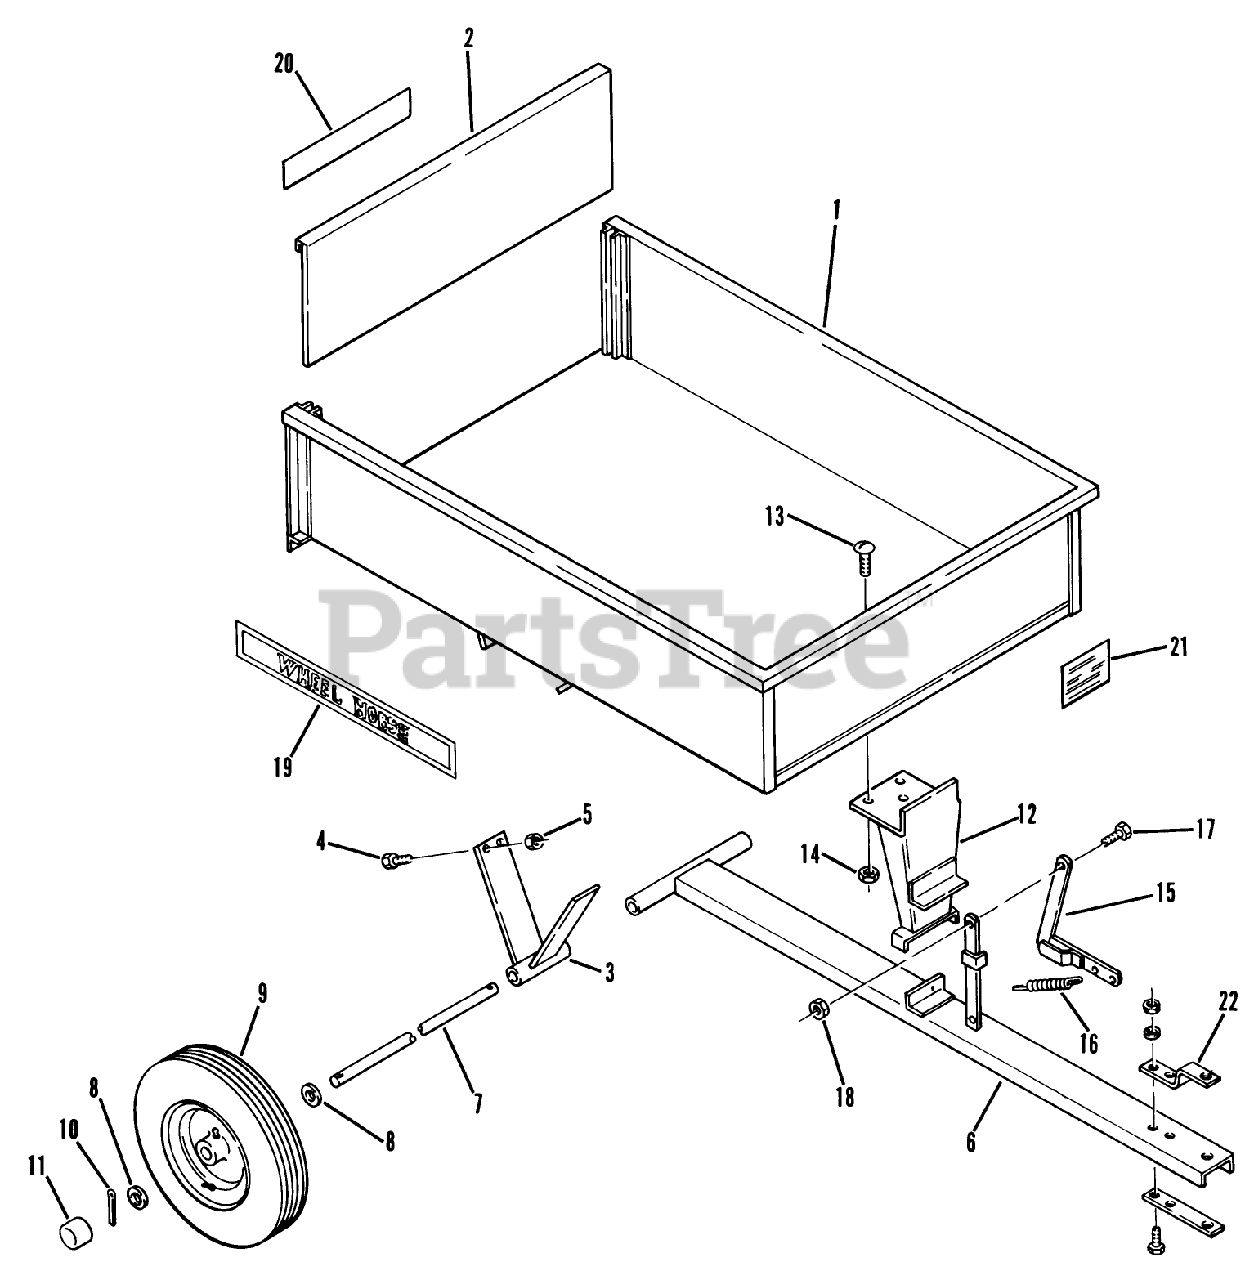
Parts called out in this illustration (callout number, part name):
1	Bed Assembly
2	Rear Gate
3	Axle Holder Assembly
4	BOLT
5	Nut
6	Drawbar Assembly
8	Special Washer
9	Wheel Assembly (4.30-8)
11	HUB CAP
12	Drawbar Spacer Assembly
13	Truss Hd. Bolt 3/8-16 x 3/4
14	Nut
15	Latch Assembly
16	SPRING
17	Bolt
18	Nut
19	DECAL-WHEEL HORSE
20	Decal
21	Weight Limit
22	Clevis
